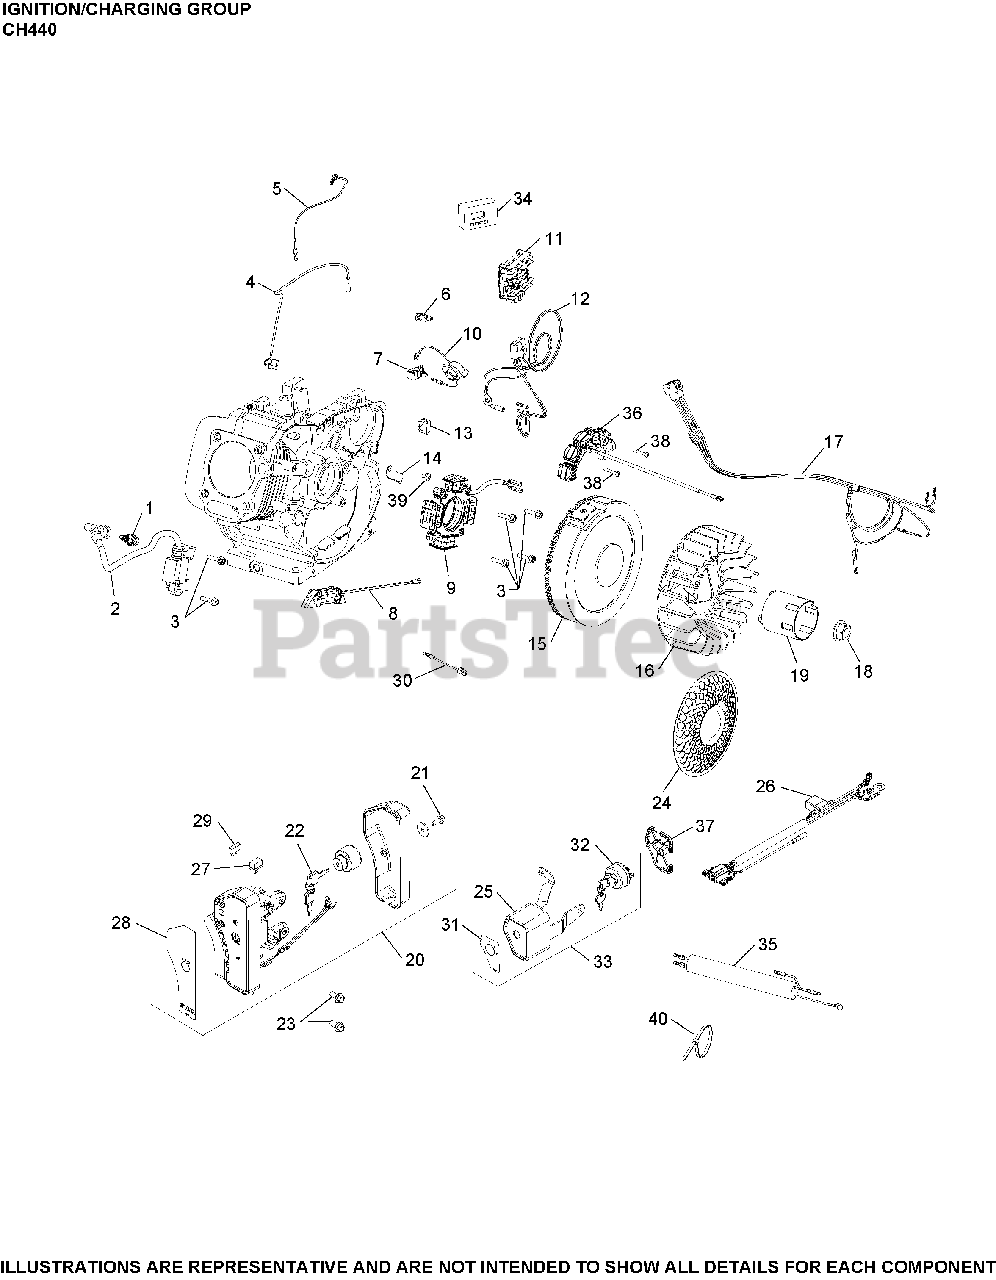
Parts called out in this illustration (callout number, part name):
1	SPARK PLUG
2	MODULE, IGNITION
3	SCREW, M6 X 25 USE 25 086 436-S
4	LEAD, GROUND TO KILL
6	LEAD, OPTIONAL EQUIPMENT
14	BRACKET, STATOR WIRE
15	FLYWHEEL ASSY ELECTRIC START (CH440)
16	FAN, FLYWHEEL
18	NUT, FLYWHEEL
19	CUP, STARTER DRIVE
21	SCREW, HEX FLANGE (M6)-USE 25 086 433-S
36	STATOR ASSEMBLY, 1 AMP
38	SCREW, STATOR MOUNTING (CKY)
39	SCREW, COIL BRACKET (CKY)
